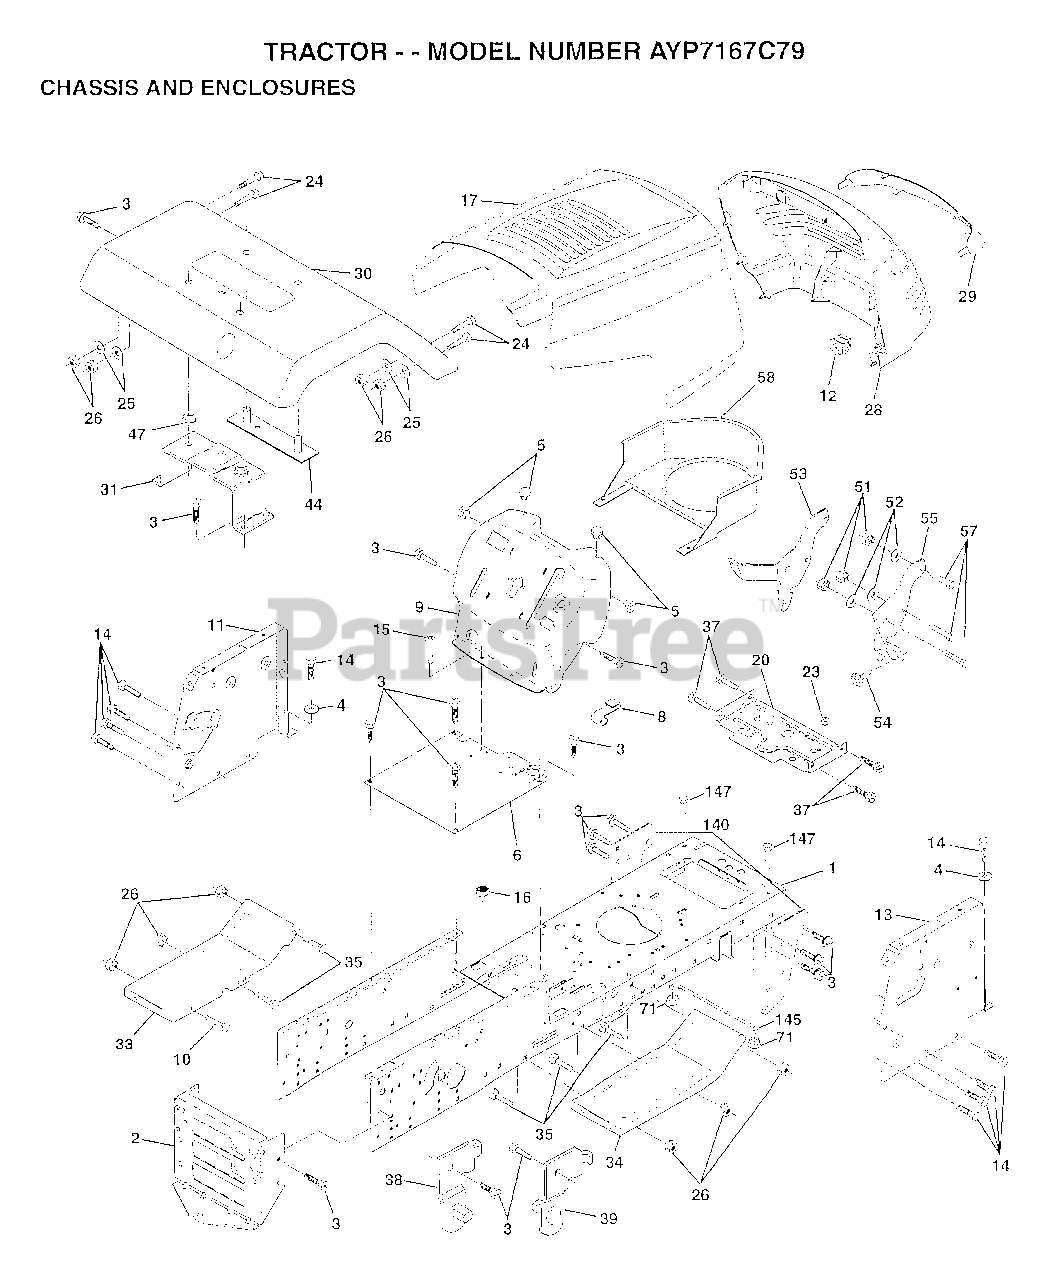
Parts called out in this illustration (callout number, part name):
1	CHASSIS ASM
3	SCREW
4	WASHER
5	BUMPER-HOOD/DASH
6	SADDLE
8	"CLIP,INSULATOR"
9	DASH SILKSCREEN
11	"PANEL-DASH,LH"
12	CLIP.TINNERMAN
13	"PANEL-DASH,RH"
14	SCREW LT
15	SCREW
17	HOOD.STL.PRV.LB
20	"PLATE-MTG,BATT/FU"
24	BOLT
25	WASHER
26	NUT
28	GRILL
29	LENS.EURO.W/DECAL
31	BRKT.ASM.FENDER
33	FOOTREST.LT.LT/GT
34	FOOTREST.RH.LT/GT
35	BOLT
37	SCREW LT
38	BRACKET ASM LH
39	BRACKET ASM RH
44	STRAP ASM FENDER
47	NUT-PUSH YT
51	NUT
52	WASHER
53	BRACKET.GRILLE.LH
55	BRACKET.GRILLE.RH
58	AIR DUCT
140	BRKT SUSPENSION
145	"ROD POVOT,CHASSIS"
147	BOLT LT
